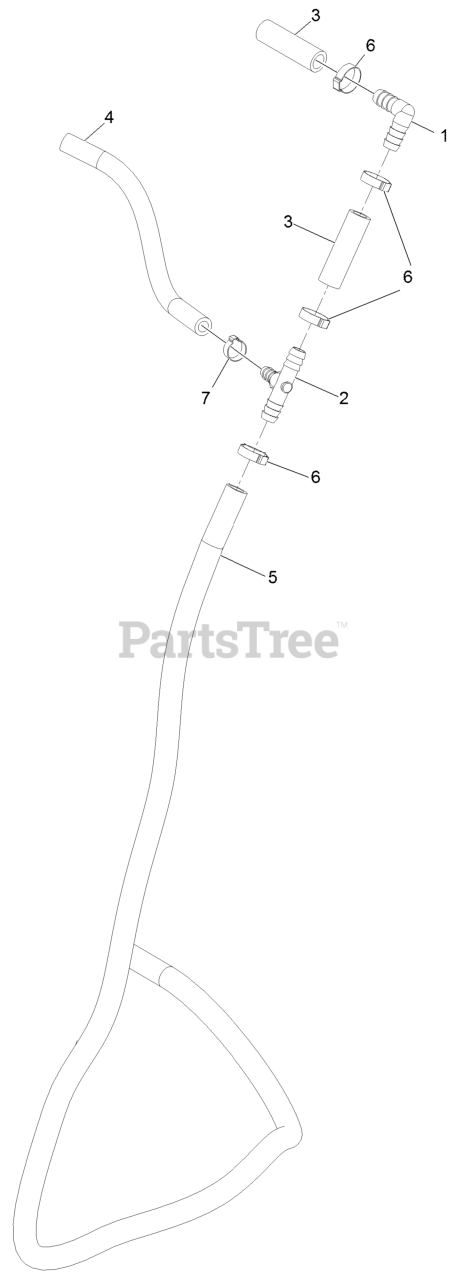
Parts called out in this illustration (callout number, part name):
1	FITTING-ELBOW-90
2	CONNECTOR-TEE
3	HOSE-WATER
4	HOSE-WATER
5	HOSE-WATER
